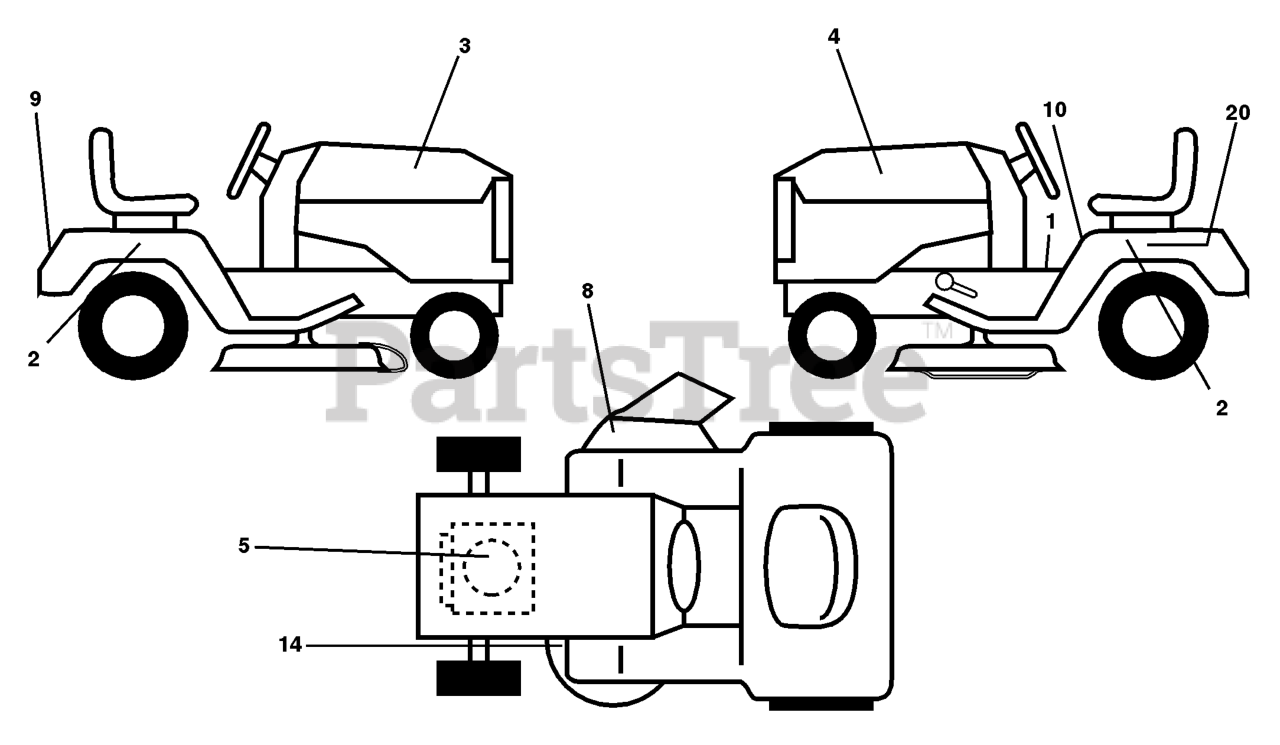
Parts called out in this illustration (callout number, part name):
3	DECAL HOOD RH
4	DECAL HOOD LH
5	DECAL HP ENGINE
8	DECAL WARNING (ENGLISH/FRENCH)
9	DECAL FENDER HUSQ
10	DECAL FENDER DANGER
14	DECAL V BELT SCHEMATIC
20	DECAL BTRY SYMBOLS
